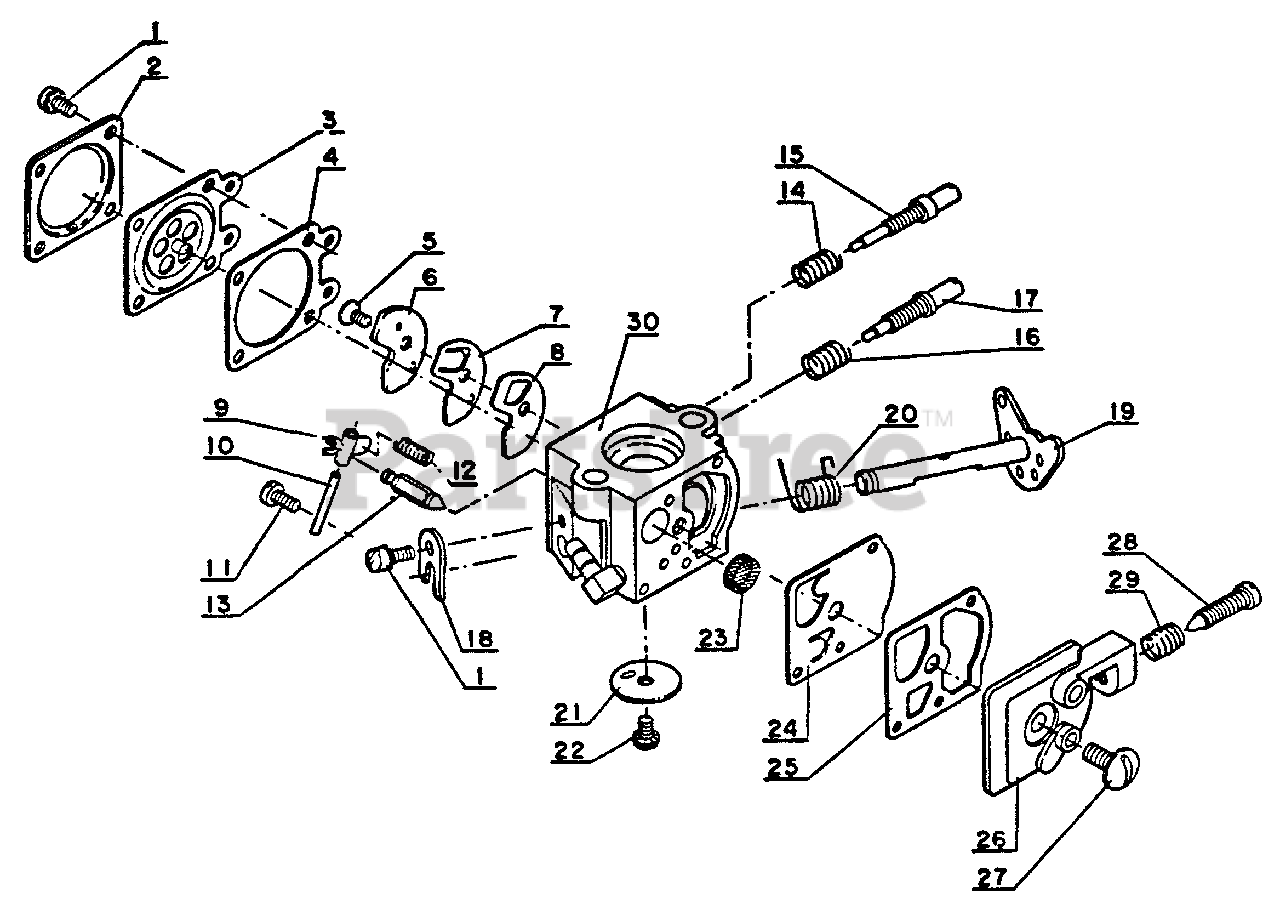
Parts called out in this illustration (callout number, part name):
1	SCREW
2	COVER, METERING
3	DIAPHRAGM, METERING
4	GASKET, METERING
5	SCREW, CIRCUIT PLATE
6	PLATE, CIRCUIT
7	DIAPHRAGM, CIRCUIT PLATE
8	GASKET, CIRCUIT PLATE
9	LEVER, METERING
10	PIN, METERING LEVER
11	SCREW, METERING LEVER PIN
12	SPRING, METERING LEVER
13	VALVE, INLET NEEDLE
14	SPRING, HIGH SPEED NEEDLE
15	NEEDLE - HIGH SPEED
16	SPRING, IDLE ADJUST
17	NEEDLE - LOW SPEED
18	CLIP, THROTTLE SHAFT
19	SHAFT, THROTTLE
20	SPRING, THROTTLE RETURN
21	VALVE, THROTTLE
23	STRAINER
24	DIAPHRAGM, PURGE
25	GASKET, PURGE
26	COVER, PUMP
27	SCREW, PUMP COVER
28	SCREW, IDLE ADJUST
29	SPRING, IDLE ADJUST
30	BODY, CARBURETOR
